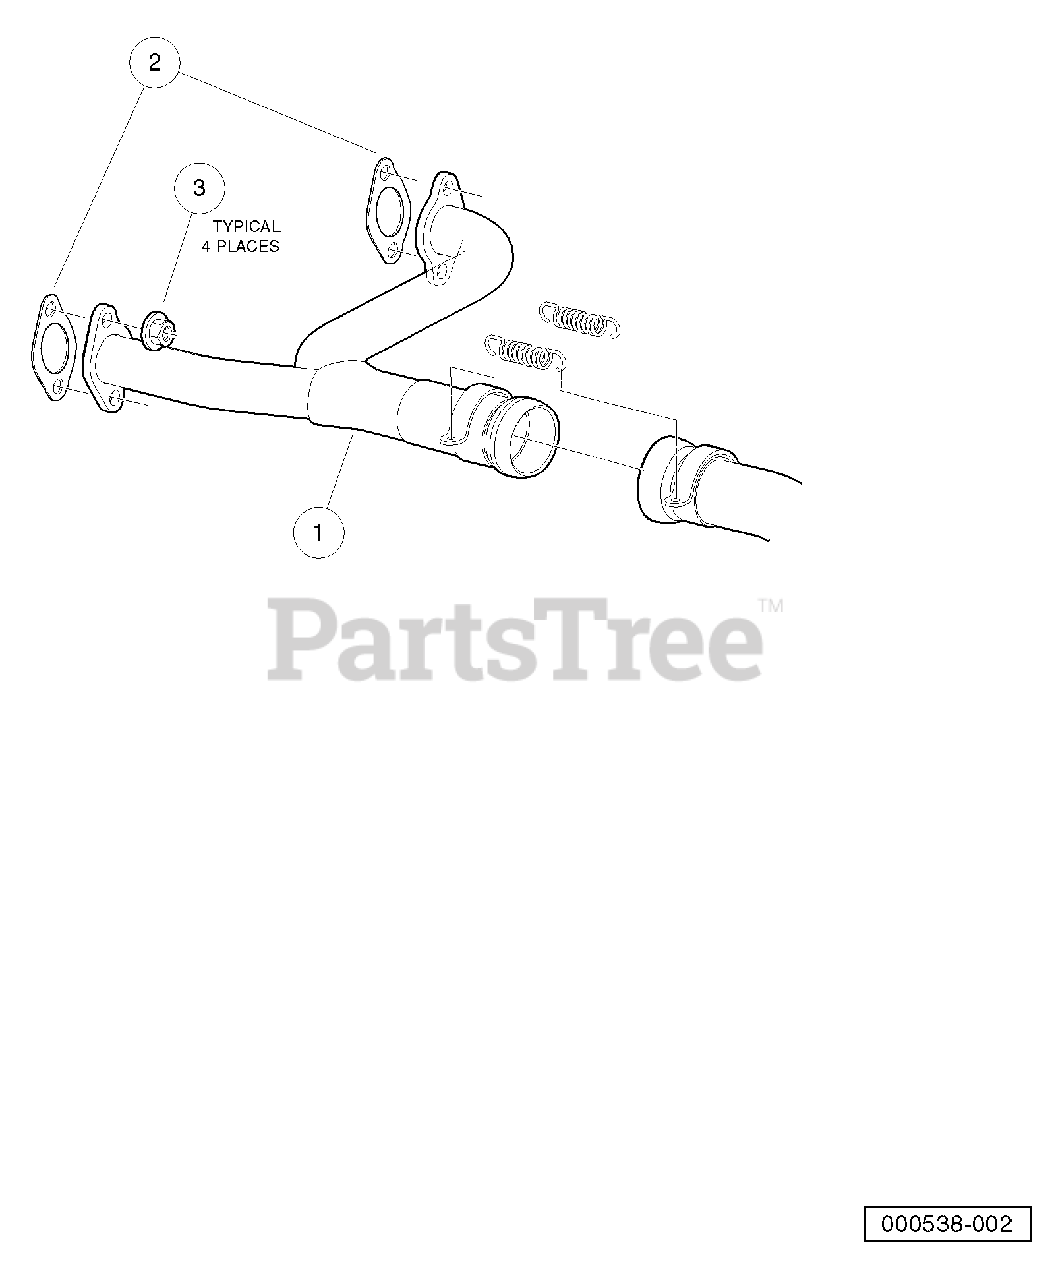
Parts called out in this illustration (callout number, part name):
1	Header, Exhaust, Gas
2	Gasket, Exhaust, Gx620
3	Nut Flg, M8 X 1.25 Serrated
